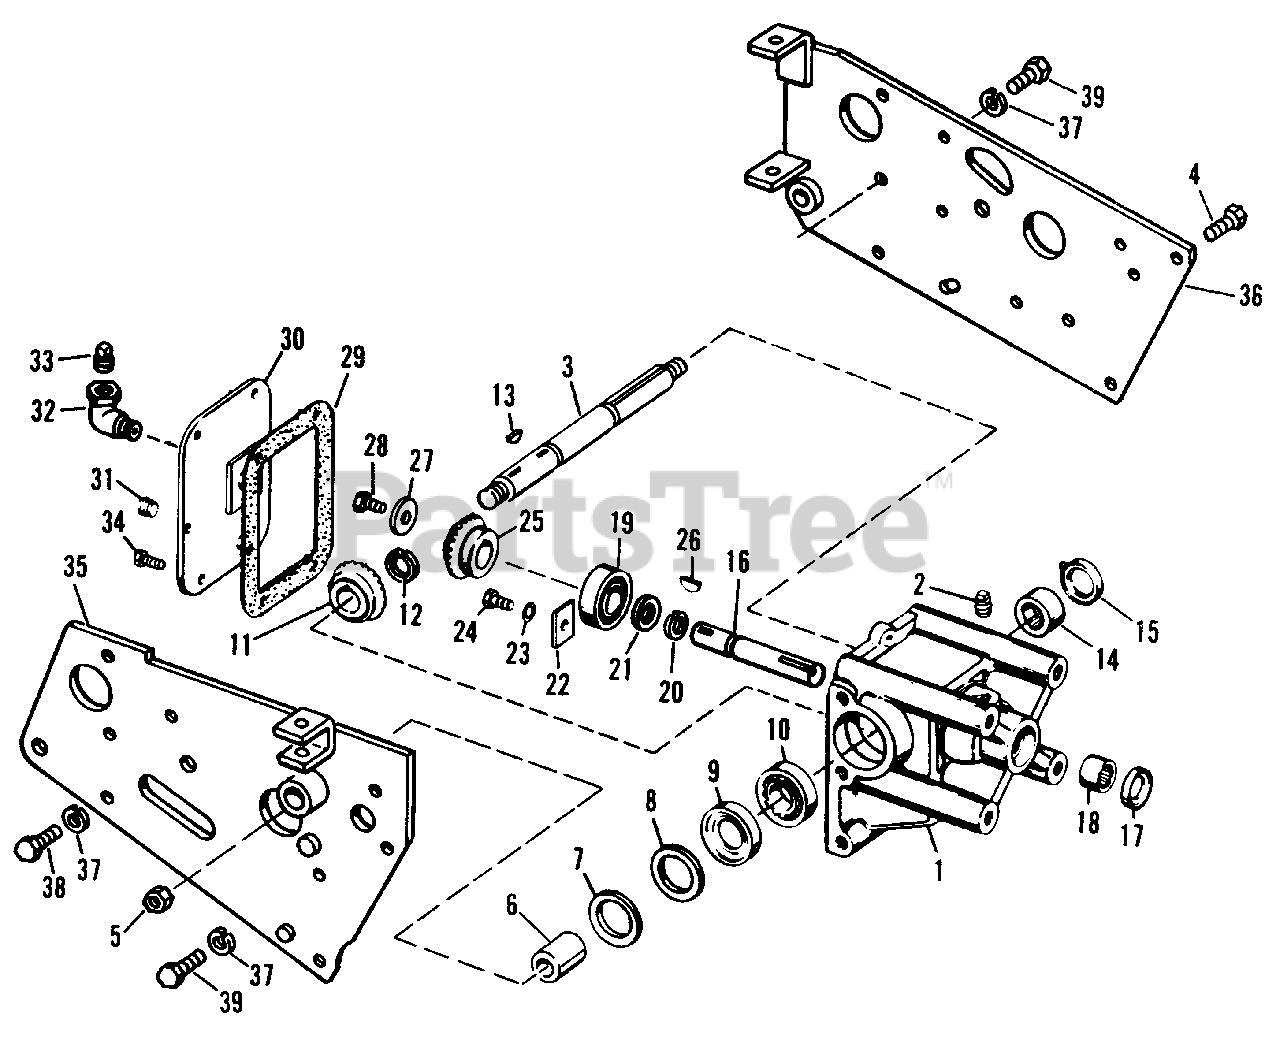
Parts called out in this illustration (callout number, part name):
1	Bevel Gear Housing, w/Bearings
2	Pipe Plug
3	Driven Shaft
4	Hex Capscrew, 7/16"-14 x 1-1/4"
5	Hex Jam Nut
7	Shim (As Required)
10	Ball Bearing
11	Bevel Driven Gear
12	Retaining Ring
14	Needle Bearing
16	Drive Shaft
18	Needle Bearing
19	Ball Bearing
20	Retaining Ring
22	Bearing Clamp Plate
23	Lockwasher, 5/16"
24	Hex Capscrew, 5/16"-18 x 5/8"
25	Bevel Driven Gear
28	Hex Capscrew, 5/16"-18 x 3/4"
30	Housing Cover Assembly
31	Pipe Plug
32	Street Elbow
33	Pipe Plug
34	Hex Capscrew, 1/4"-20 x 5/8"
35	Right Hand Side Plate
36	Left Hand Side Plate
37	Lockwasher, 7/16"
38	Hex Capscrew, 7/16"-14 x 1"
39	Hex Capscrew, 7/16"-14 x 1-1/4"
